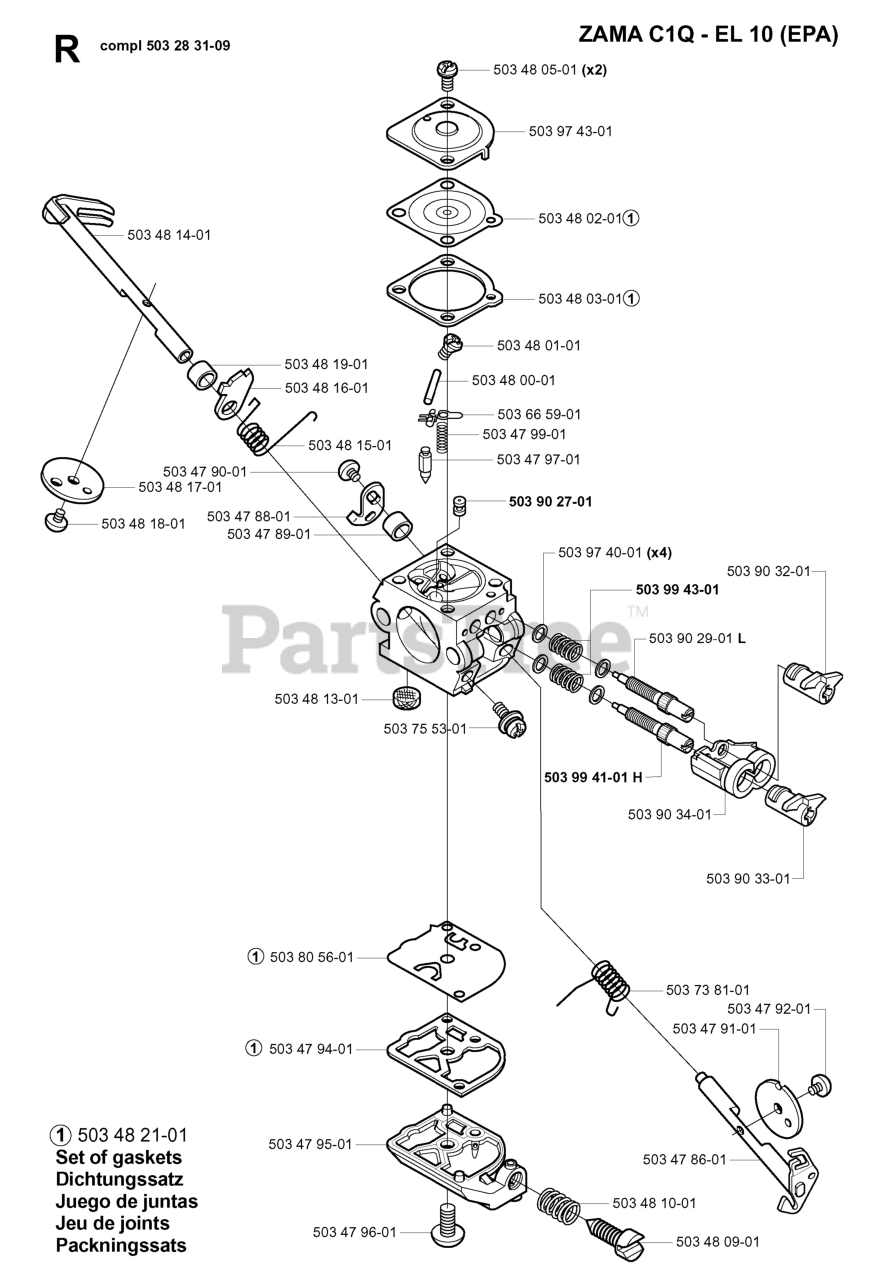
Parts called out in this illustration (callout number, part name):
2	DRAWBAR.STGT
3	APPLIQUE.SUBASM.GT.HUSQ.II
5	DASH.UPR.ASM.GT2.SRV.MIN.PTO
14	HOOD.ASM.HUSQVARNA.GT.TEX.ORAN
15	LENS.HEADLIGHT.LH.GTII.2011
18	GRILLE.SUBSTRATE.2011.
19	WASHER
25	LENS.HEADLIGHT.RH.GTII.2011
36	SCREW 5/16"
37	FENDER.PNT.TX.GT.CH/FW/DL.HUSQ
58	BRKT.SUPPORT.FNDR/TANK
68	Screw 5/16-18 x 1/2 Hex, Self Tapping 5/16-18 x 1/2
130	SCREW.#10 X 0.750.BOS
137	BUMPER DASH
150	AIR.DUCT.GTV.BLACK
151	BRACKET.PIVOT.HOOD.GT.HUSQ.II
152	SHIELD.BROWNING.PNT.GT.V2
159	SCREW, 3/8-16X3/4
161	CONSOLE.WINDOW.FUEL.HUSQ.GT
162	SCREW.HI-LO.CONSOLE
165	SUPPORT.TANK.REAR.B/TE
175	PLATE.CROSSMEMBER.HUSQ
176	SCREW.#10-24X5/8.RN.QU
177	BUSHING, STEERING
178	CARGO.ASM.NET.TXGT.W/C
180	CHASSIS.TEX.BOLTED
182	DASH.LOWER.COMMON.12V.ADAPTOR
183	BOLT.5/16-18X1-1/4 FULL THD
189	SCREW
191	INSERT.REFLECTIVE.RH.HUSQ.GTII
194	NUT LOCK HEX FLANGE 5/16-18
196	CONSOLE.ASM.DECKLIFT.HUSQGT.DL
199	PLATE.DECK.LIFT.HUSQVARNA.GT
202	VENT.SIDE.RH.GT.HUSQ.II.
203	VENT.SIDE.LH.GT.HUSQ.II.498
204	VENT.TOP.HUSQ.GT2
205	SIDE.TRIM.RH.GT.HUSQ.II
206	SIDE.TRIM.LH.GT.HUSQ.II.GRAY
207	BEZEL LIGHT.RH.GT.II.MYLAR
208	BEZEL LIGHT.LH.GT.II.MYLAR
214	CLIP.RETAINER.TINNER.
217	ROD.PIVOT.HOOD
221	REFLECTOR.LH.TEX GT HU
228	STUD.FASTNER.W/ANTI-ROTATE
234	BUMPER.HOOD.TEX.HUSQVARNA
235	SPACER FENDER
236	NUT.CENTERLOCK.5/16-
297	INSERT.REFLECTIVE.LH.HUSQ.GTII
335	COVER.LOWER.DASH.RH.BLACK
336	COVER-LH.LOWER.DASH.GT2.BLACK
350	CLIP.X-MAS.TREE
351	PIN.CLEVIS.375X2.125
352	PIN.CLEVIS.(.375 X 1.25)
353	CLIP RETAINER
354	SUPPORT.BELLCRANK
355	BELLCRANK.PIVOT.LOCK.DIFF
356	LINK.LOCK.DIFF
357	SPRING.COMPRESSION
358	GUIDE.SWIVEL
359	ACTUATOR.ELECTRIC
360	BRACKET.ACUATOR
361	SCREW LT.3/8-46X5/8
362	PIN.CLEVIS.(.375 X 2.42)
365	SPACER.NYLON.75" X .4375
